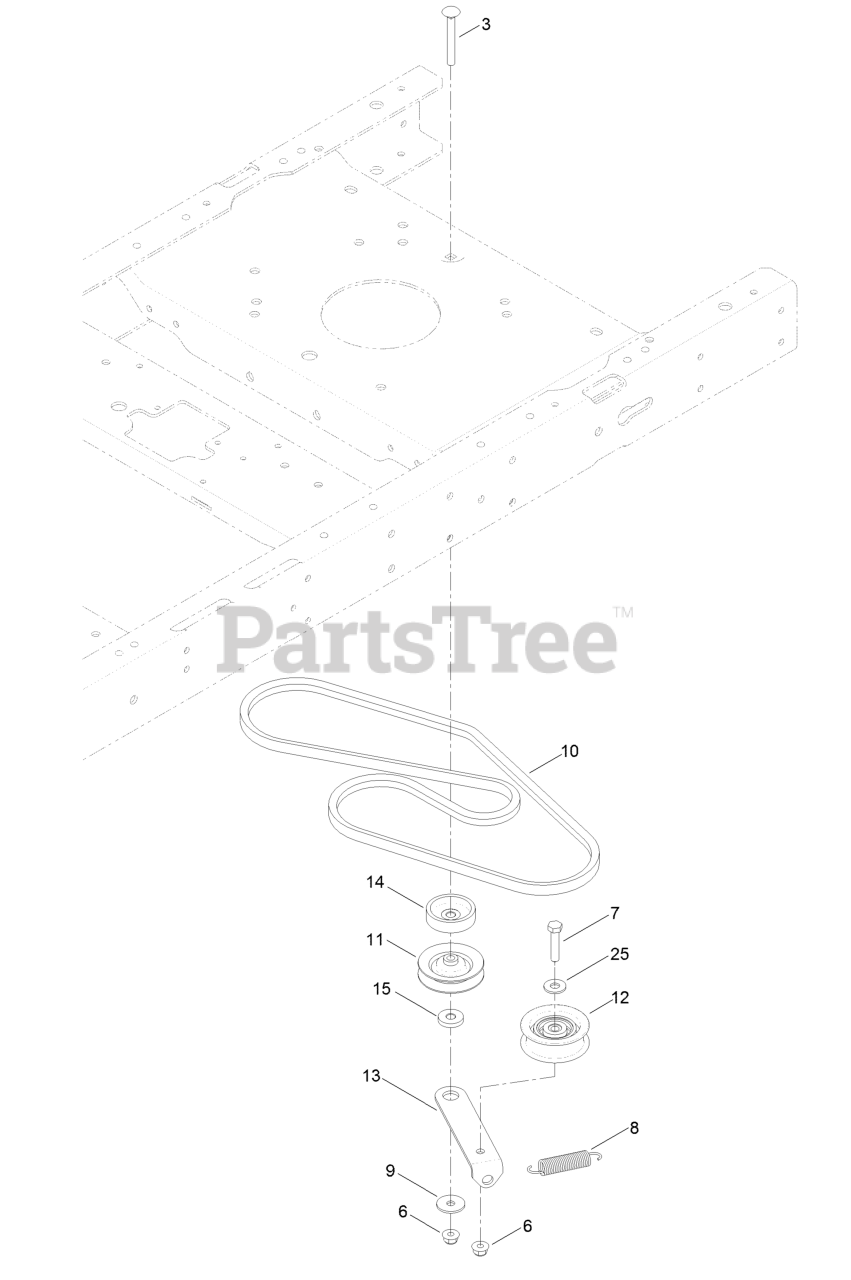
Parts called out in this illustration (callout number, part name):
3	SCREW-CARR
6	NUT-HF, NI
7	SCREW-HH
8	SPRING-RETURN, PEDAL
9	WASHER-PIVOT
10	V-BELT
11	PULLEY-IDLER
12	PULLEY-IDLER
13	ARM-IDLER
15	SPACER-ARM, IDLER
25	WASHER-FLAT
